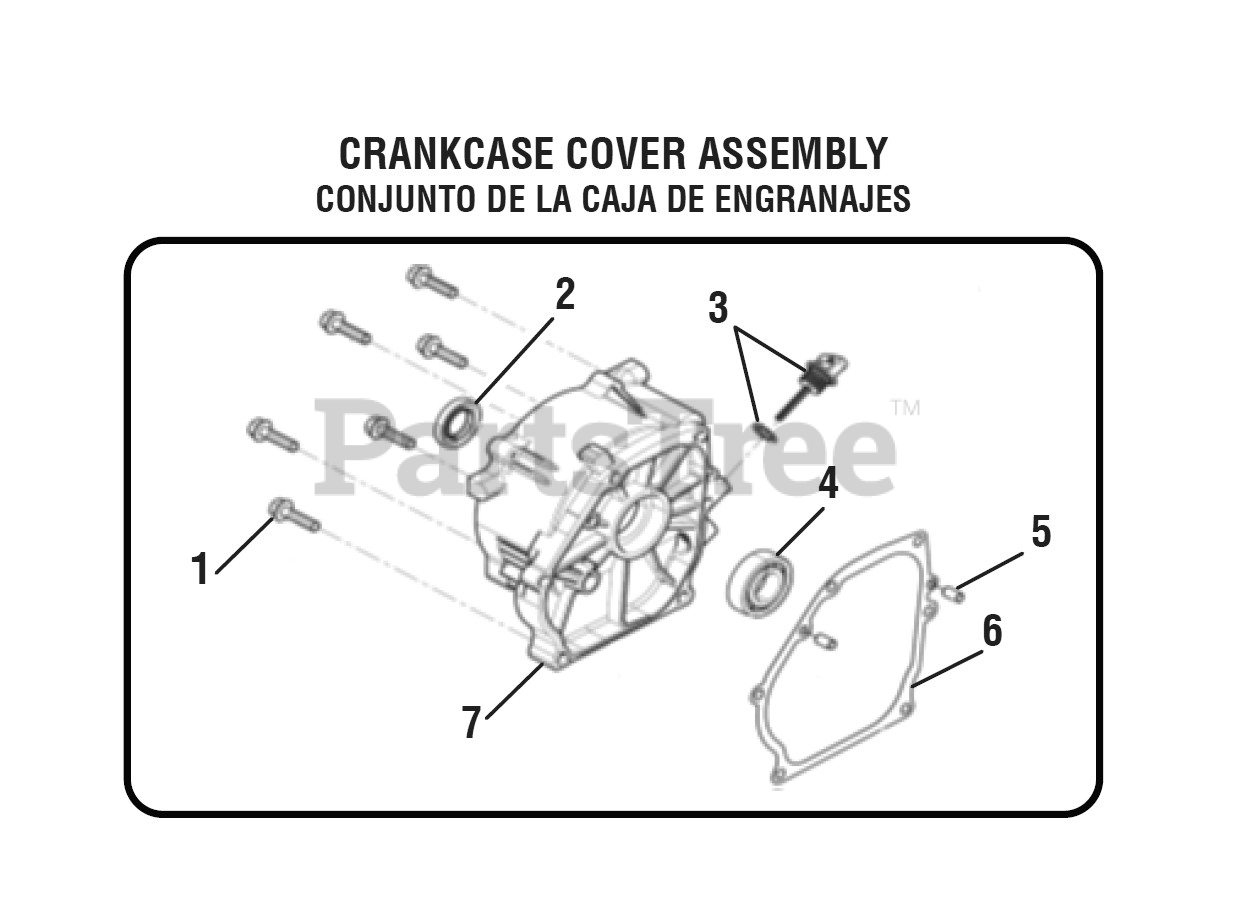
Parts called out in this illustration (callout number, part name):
2	Oil Seal
3	Oil Dipstick Assembly
4	Ball Bearing
6	Crankcase Gasket
7	Crankcase Cover
